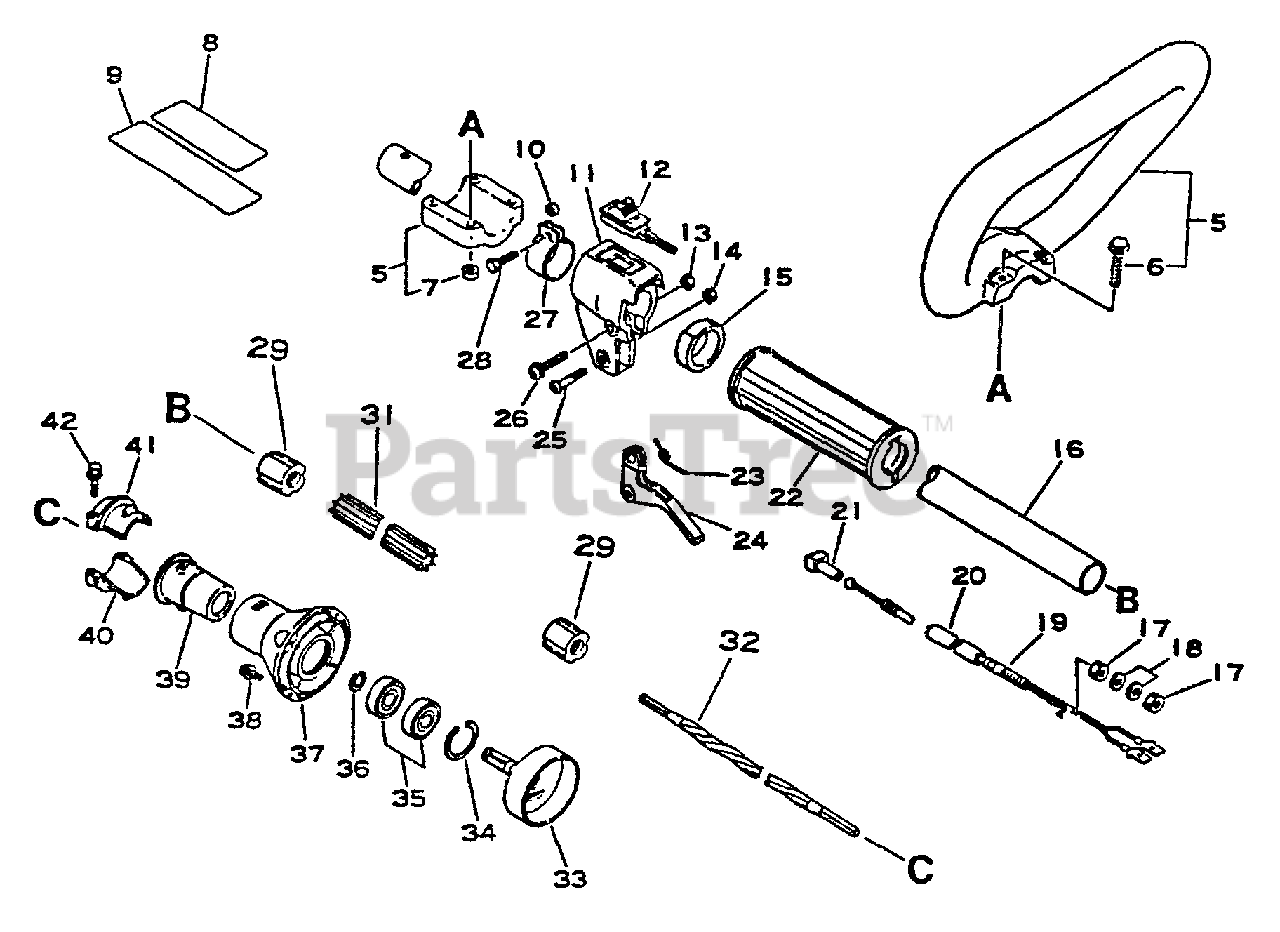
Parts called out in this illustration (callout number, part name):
5	LOOP HANDLE ASSY
6	SCREW - 5X35
8	LABEL - CAUTION
9	LABEL - CAUTION
11	BRACKET, THROTTLE CONTROL
12	IGNITION SWITCH ASSY
14	LOCKNUT - 5
16	MAIN PIPE ASSY
18	WASHER - 6
19	CABLE, THROTTLE
20	TUBE - VINYL
21	GUIDE, CABLE
22	GRIP, HANDLE
23	SPRING, TRIGGER
24	TRIGGER, THROTTLE
25	SCREW - 5X30
26	SCREW - 5X30
28	BOLT - 5X18
31	LINER - FLEXIBLE
32	DRIVESHAFT - FLEXIBLE
33	DRUM, CLUTCH
34	RING, RETAINING - 28
35	BEARING, BALL - 6001
36	RING, RETAINING - 12
37	CASE, CLUTCH - ORANGE
38	SCREW - 5X16
40	CLAMP, MAIN PIPE
41	CLAMP, MAIN PIPE - UPPER
42	BOLT - 5X25
